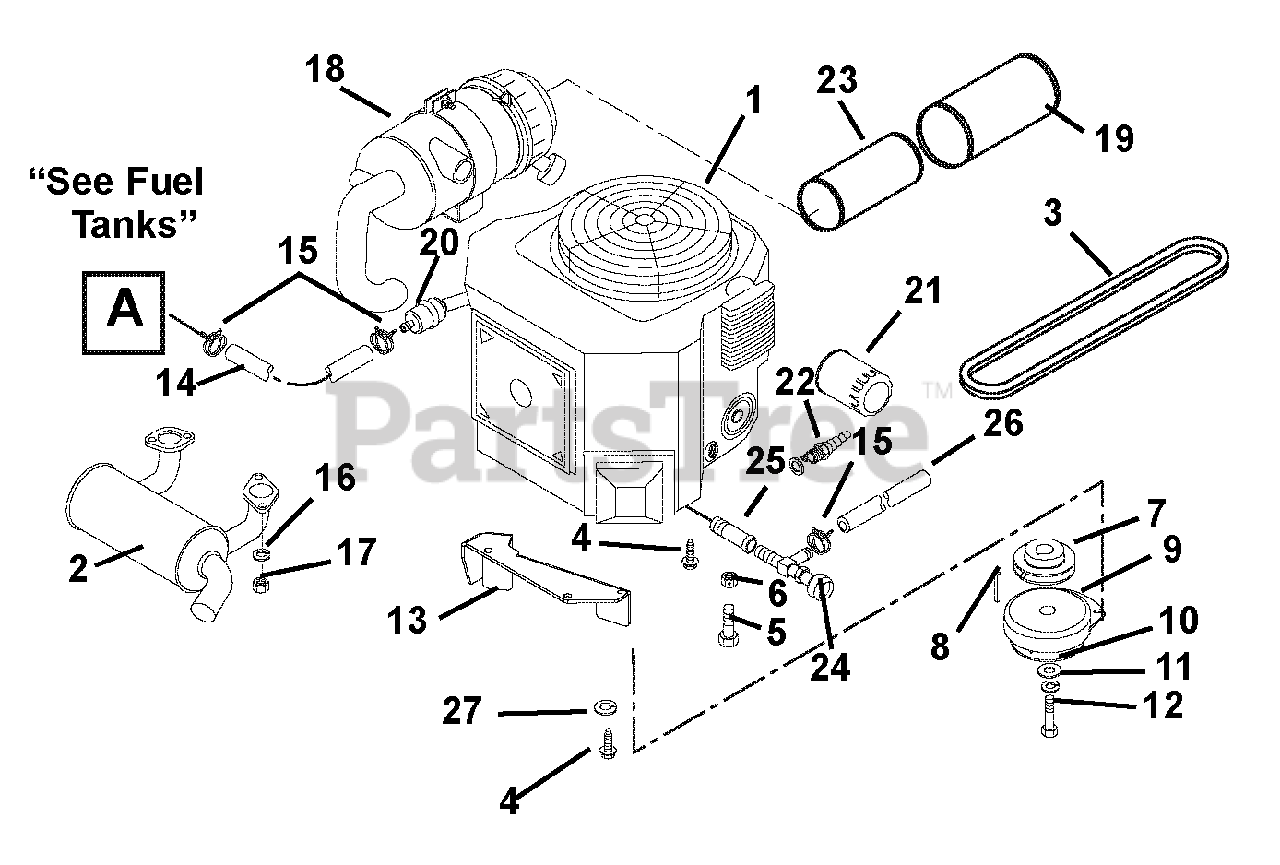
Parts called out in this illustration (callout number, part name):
1	ENGINE, KAWASAKI 21HP
2	MUFFLER, KAW (INTERMEDIATE-Z)
3	V-BELT, HA-WRAPPED
4	BLT, 38-16X1 6-LOBE PH TRX YZ
5	@BLT-HEX .31-18X1.50 GR5 YWZC
6	@NUT-LK-TOP-FLG .31-18 YWZC
7	SHEAVE, 4.831 X 1.127 ENGINE
8	KEY-SQ .25X.625X.25 SAE 8630
9	CLUTCH, WARNER 6.323 O/PIN
10	WSHR-FL-STL .515X1.625X.250 YZ
11	@WSHR-LK .44X.109 REG YWZC
12	BLT-HEX .44-20X2.50 GR5 YWZC
13	WMT, CLUTCH STOP
14	GAS LINE-BULK 1/4" I.D.
15	CLAMP-HOSE WIRE .490/.510X.116
16	@WSHR-LK .31X.078 REG YWZC
17	NUT-HEX M8-1.25 YWZC
18	AIR CLEANER ASSEMBLY
19	ELEMENT, OUTER PRIMARY
20	FILTER, FUEL - KOH CV20
21	FILTER,OIL - KAW
22	PLUG, SPARK
23	ELEMENT, INNER SAFETY
24	COCK, OIL DRAIN
25	ADAPTER, OIL DRAIN
26	GAS LINE-BULK 1/4" I.D.
27	@WSHR-LK .31X.078 REG YWZC
